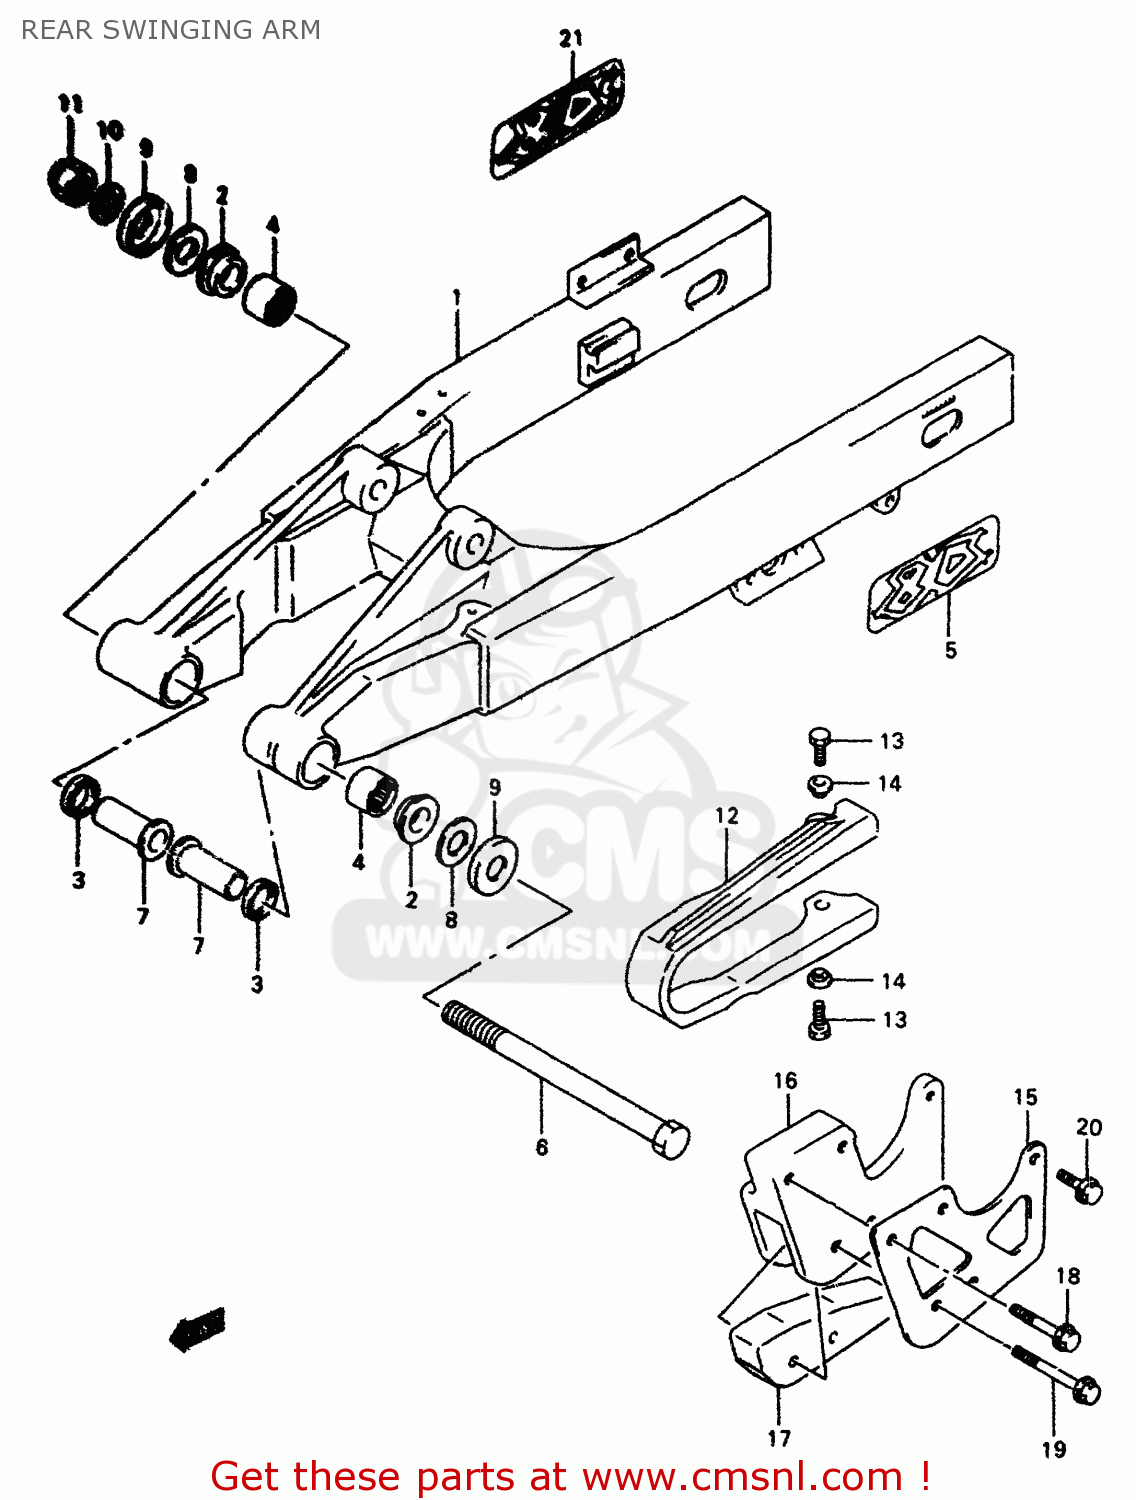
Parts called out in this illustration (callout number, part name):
1	SWINGINGARM ASSY,RR
2	BUSHING,SWGARM PIVOT
3	SEAL,OIL(17X24X3)
4	BEARING(17X24X30)
5	EMBLEM,SWING ARM
6	SHAFT,RR SWINGINGARM PIVOT
7	SPACER,RR SWGARM PIVOT
8	WASHER
9	COVER,SWGARM PIVOT
10	WASHER
11	NUT 12MM
12	BUFFER,CHAIN TOUCH DEFENSE
13	BOLT
14	WASHER
15	PLATE,GUIDE CHAIN OUTER
16	GUIDE,CHAIN
17	DEFENSE,CHAIN GUIDE
18	BOLT,G/S SWITC
19	BOLT
20	BOLT
21	EMBLEM,SWINGINGARM
